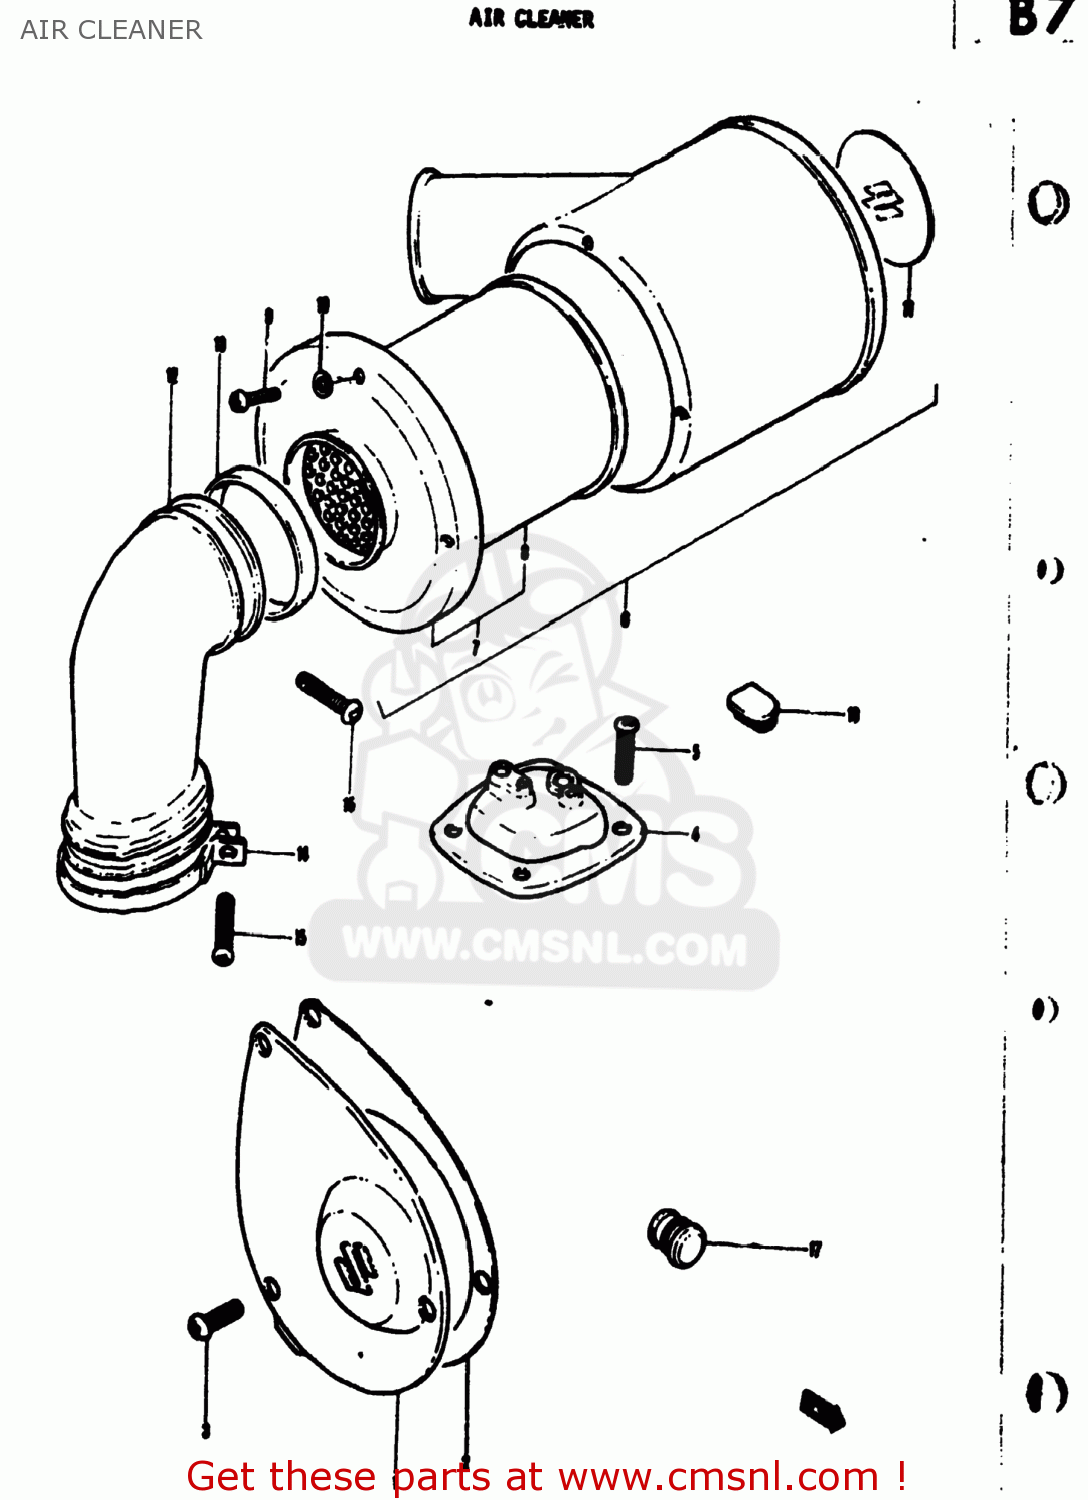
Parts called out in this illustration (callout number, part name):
1	CAP,CARBURETOR INSPECTION
2	GASKET,CARBURETOR INSPECTION (MCA)
3	SCREW
4	COVER,CARBURETOR,TOP
5	SCREW
6	CLEANER ASSEMBLY,AIR
7	FILTER ASSY
8	ELEMENT,AIR CLEANER
9	SCREW
10	WASHER
11	EMBLEM
12	TUBE,AIR CLEANER OUTLET
13	CLAMP
14	CLAMP
15	SCREW
16	CAP
17	Plug
